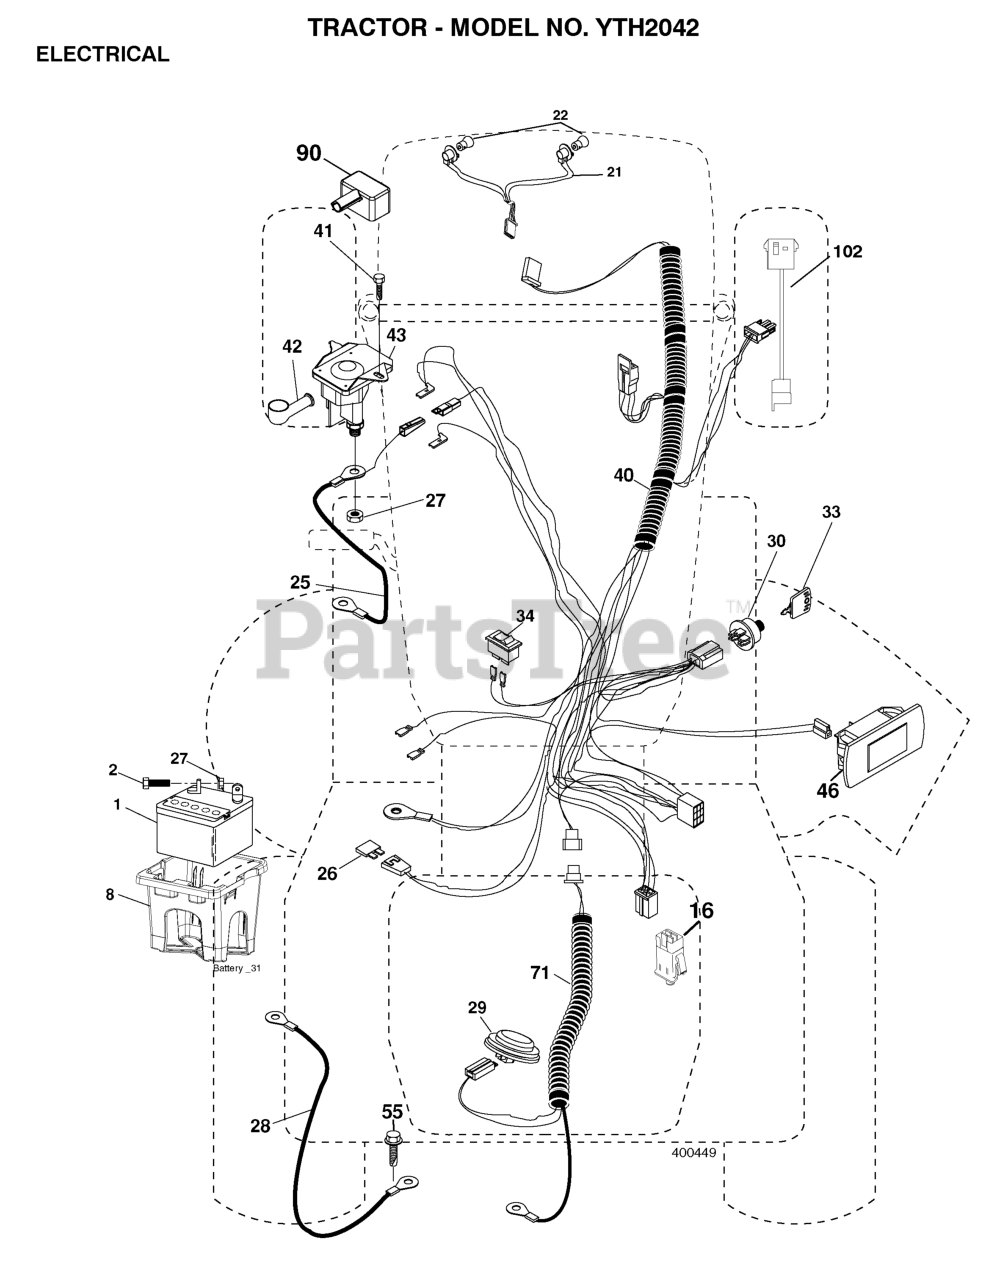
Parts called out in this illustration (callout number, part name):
1	Battery 12 Volt 25 Amp
2	BOLT.HEX.1/4.X.3/4.DICHROMATE
8	BOX.BATTERY.MNT.REAR.L
16	SWITCH INTERLOOK PUSH-IN
21	HARNESS ASSY LIGHT
25	CABLE.START.RED.17.5".
26	FUSE 20AMP
27	NUT
28	CABLE.BLACK.18"REAR.BA
29	SWITCH.SEAT.DELTA.OPC.
30	SWITCH.IGN.DELTA.W.LGH.ROS
33	KEY MLD GEN DELTA
40	HARNESS IGN. DASH
41	SCREW
42	TERMINAL COVER
43	SOLENOID.W/BRASS.PLUNGER
46	RP.GUAGE.SRVCMNDR.HRMTR.
50	RP.PTO.SWITCH.8 TERMINAL.BLACK
55	SCREW 5/16"
71	HARNESS.IGN.CHASS.TEX.REAR.BAT
90	COVER, TERMINAL BATTERY
102	HARNESS PIGTAIL PCH TEX ROS
